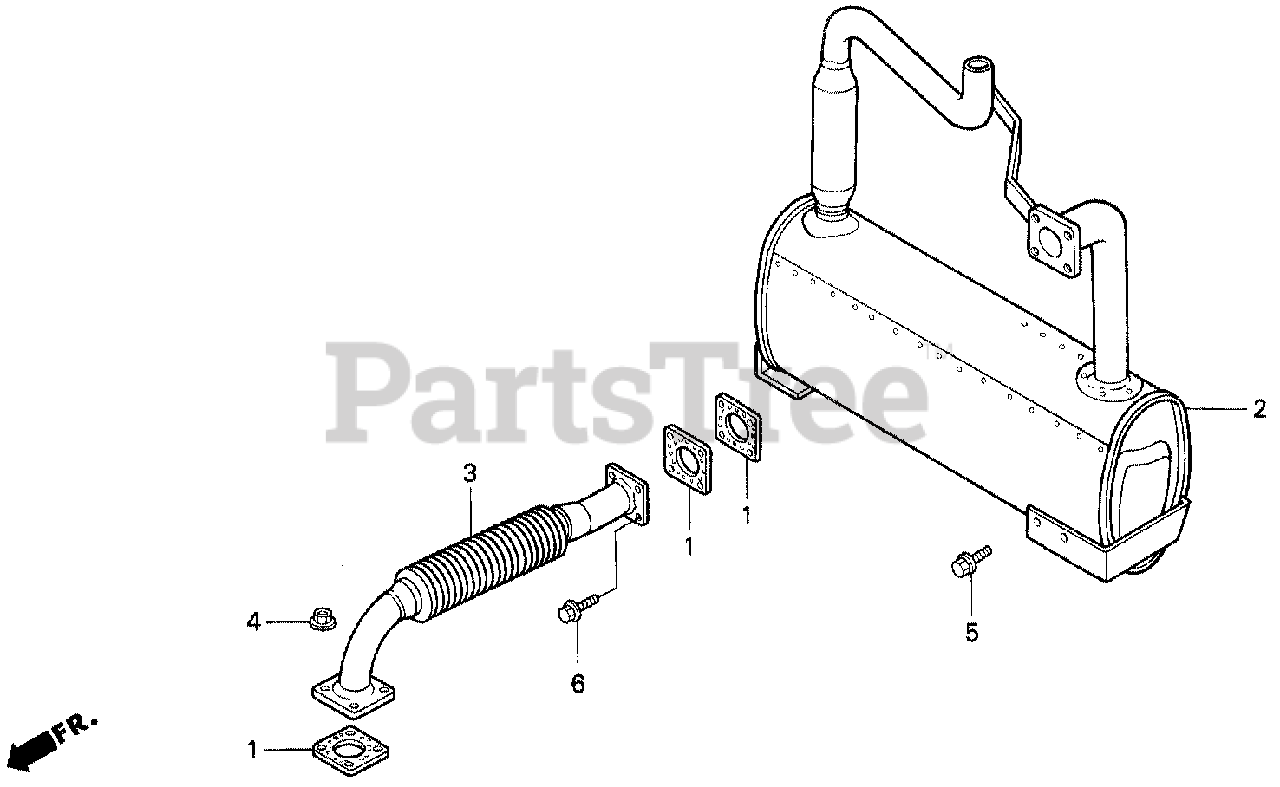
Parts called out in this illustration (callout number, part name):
1	GASKET, MUFFLER
4	NUT, FLANGE (8MM)
5	BOLT, FLANGE (8X16)
6	BOLT, FLANGE (8X25)
